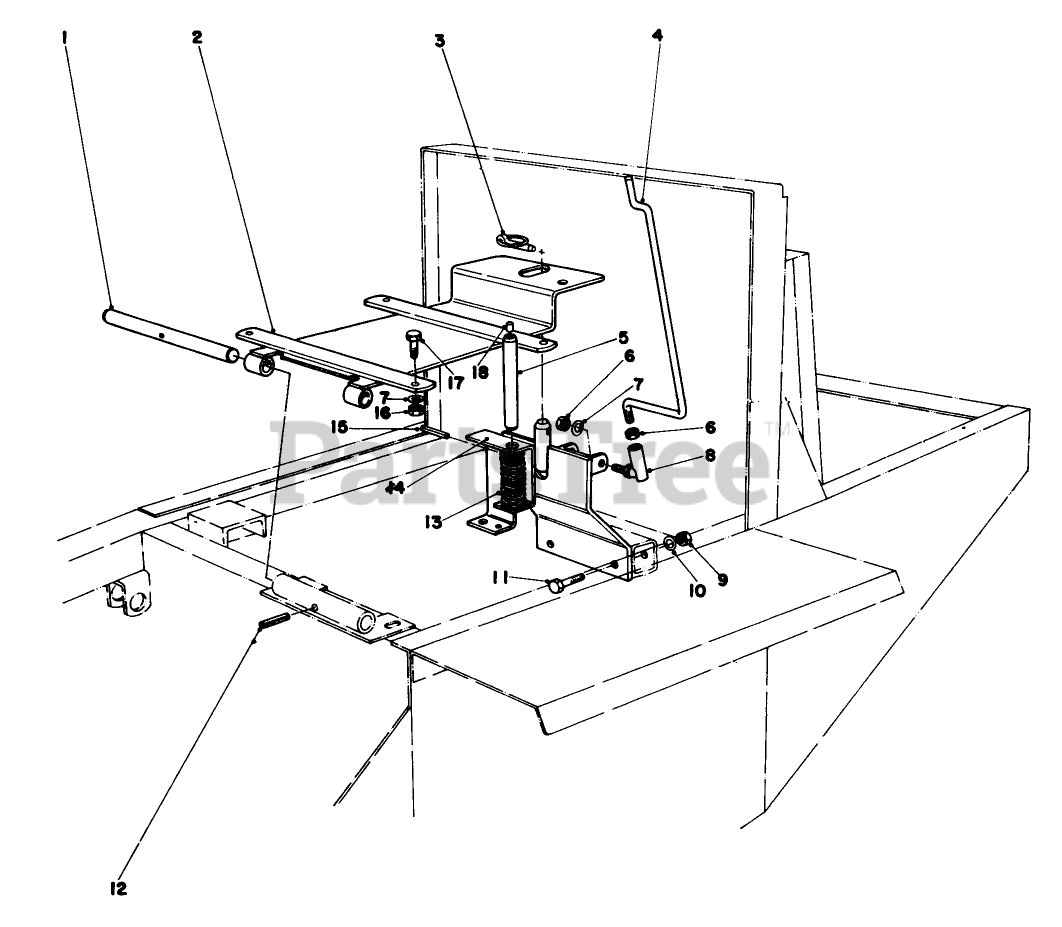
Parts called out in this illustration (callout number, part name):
1	SHAFT-PIVOT, SEAT
2	Seat Support
3	PIN-LYNCH
4	PROP SEAT
5	PIN-SWITCH, SEAT
6	NUT-JAM
7	WASHER-LOCK/SP
8	Ball Joint
9	NUT-HEX
10	WASHER-LOCK
11	SCREW-HH
12	PIN-ROLL, SLOTTED
13	SPRING-COMP
14	Bracket-Seat Support
15	PIN-ROLL, SLOTTED
16	NUT-HEX
17	Screw
18	PIN-PEDAL
38	Sleeve 14x1x19MM
